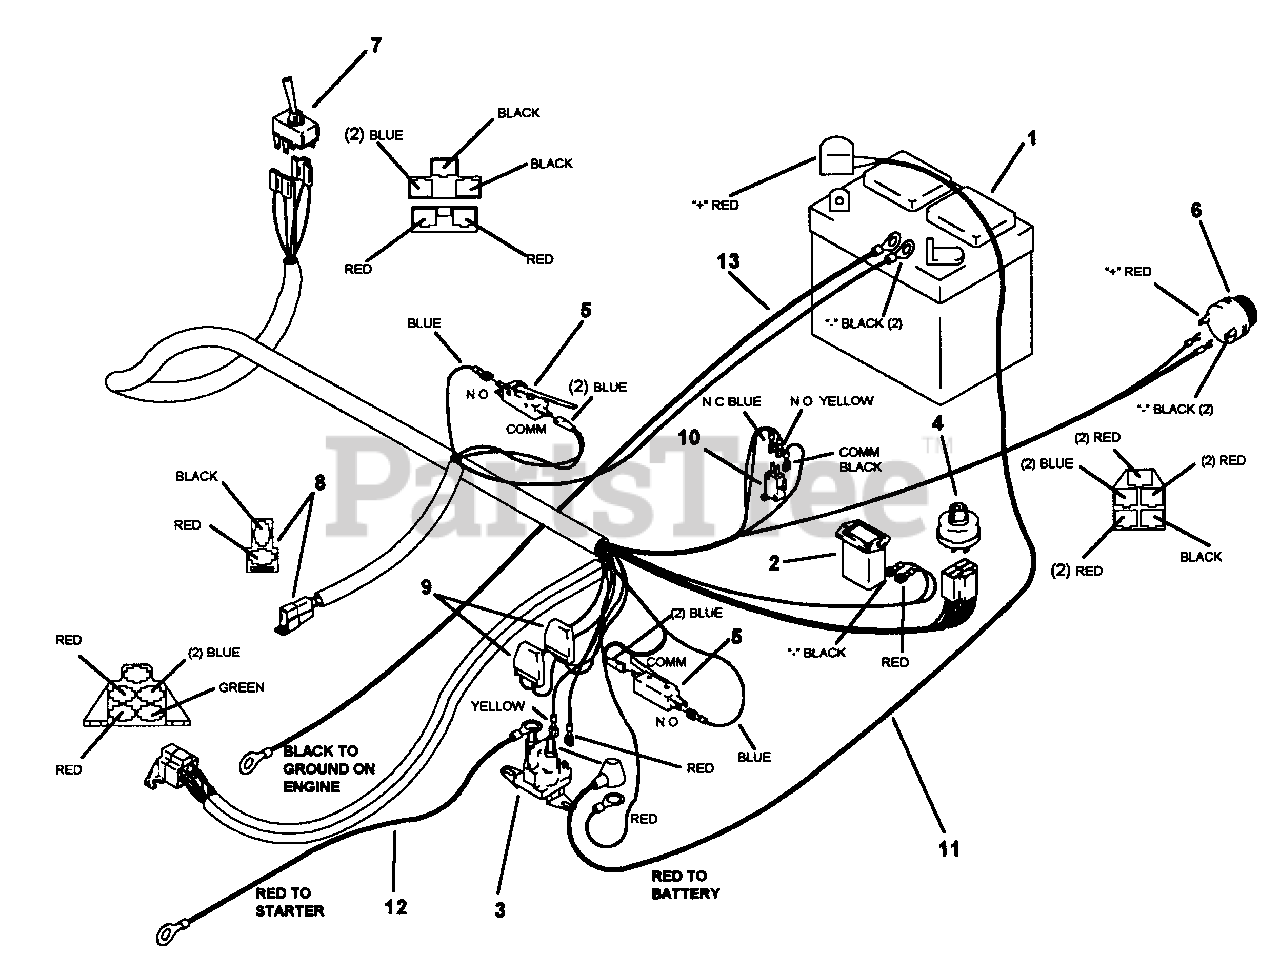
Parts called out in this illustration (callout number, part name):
1	BATTERY 12 VOLT
2	HOUR METER, 18, & 22 HP
3	SOLENOID, STARTER, 12V. INT. GRD.
4	START SWITCH
5	SWITCH, ENCL, SPDT 15A HINGED LEVER
6	BUZZER, PULSING
7	CLUTCH SWITCH
8	INSULATOR COVER (female end only)
9	FUSE, 30 AMP SPADE STYLE
10	SWITCH, SPDT MINIATURE
12	CABLE, STARTER, 31.75" WO/BOOTS
